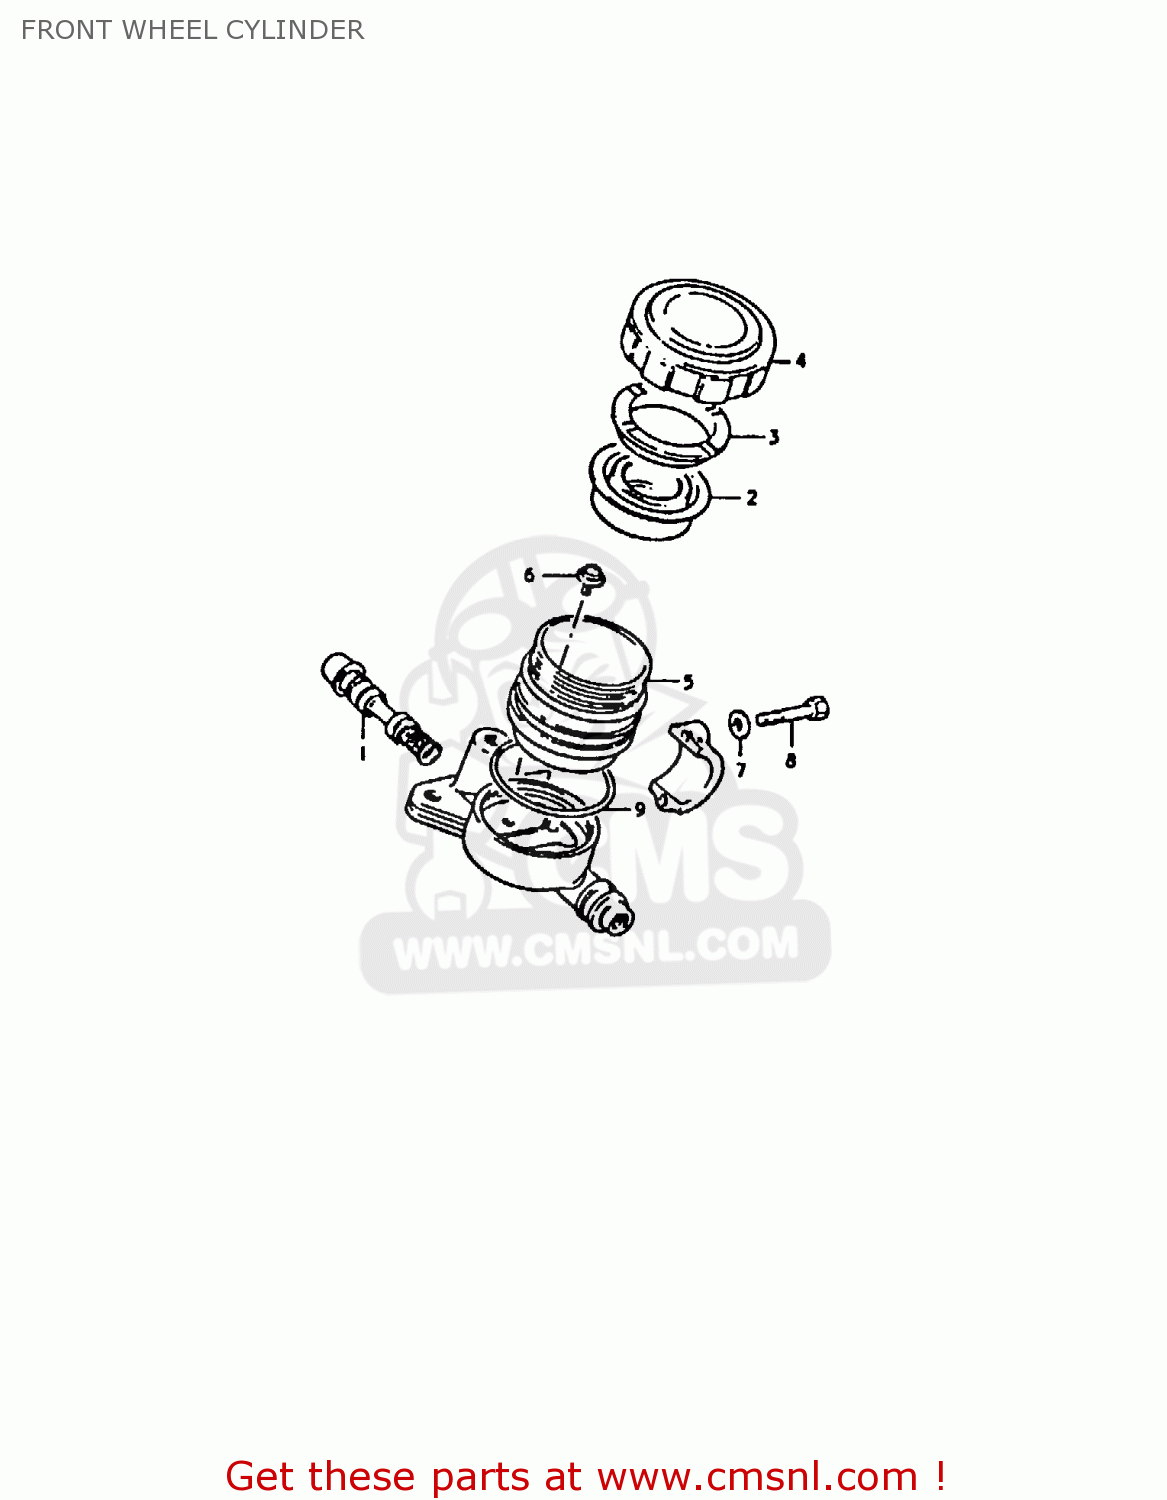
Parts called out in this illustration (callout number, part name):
1	PISTON & CUP SET
2	DIAPHRAGM
3	PLATE
4	CAP
5	RESERVOIR
6	SCREW,MASTER CYLINDER
7	WASHER
8	BOLT
9	O RING
